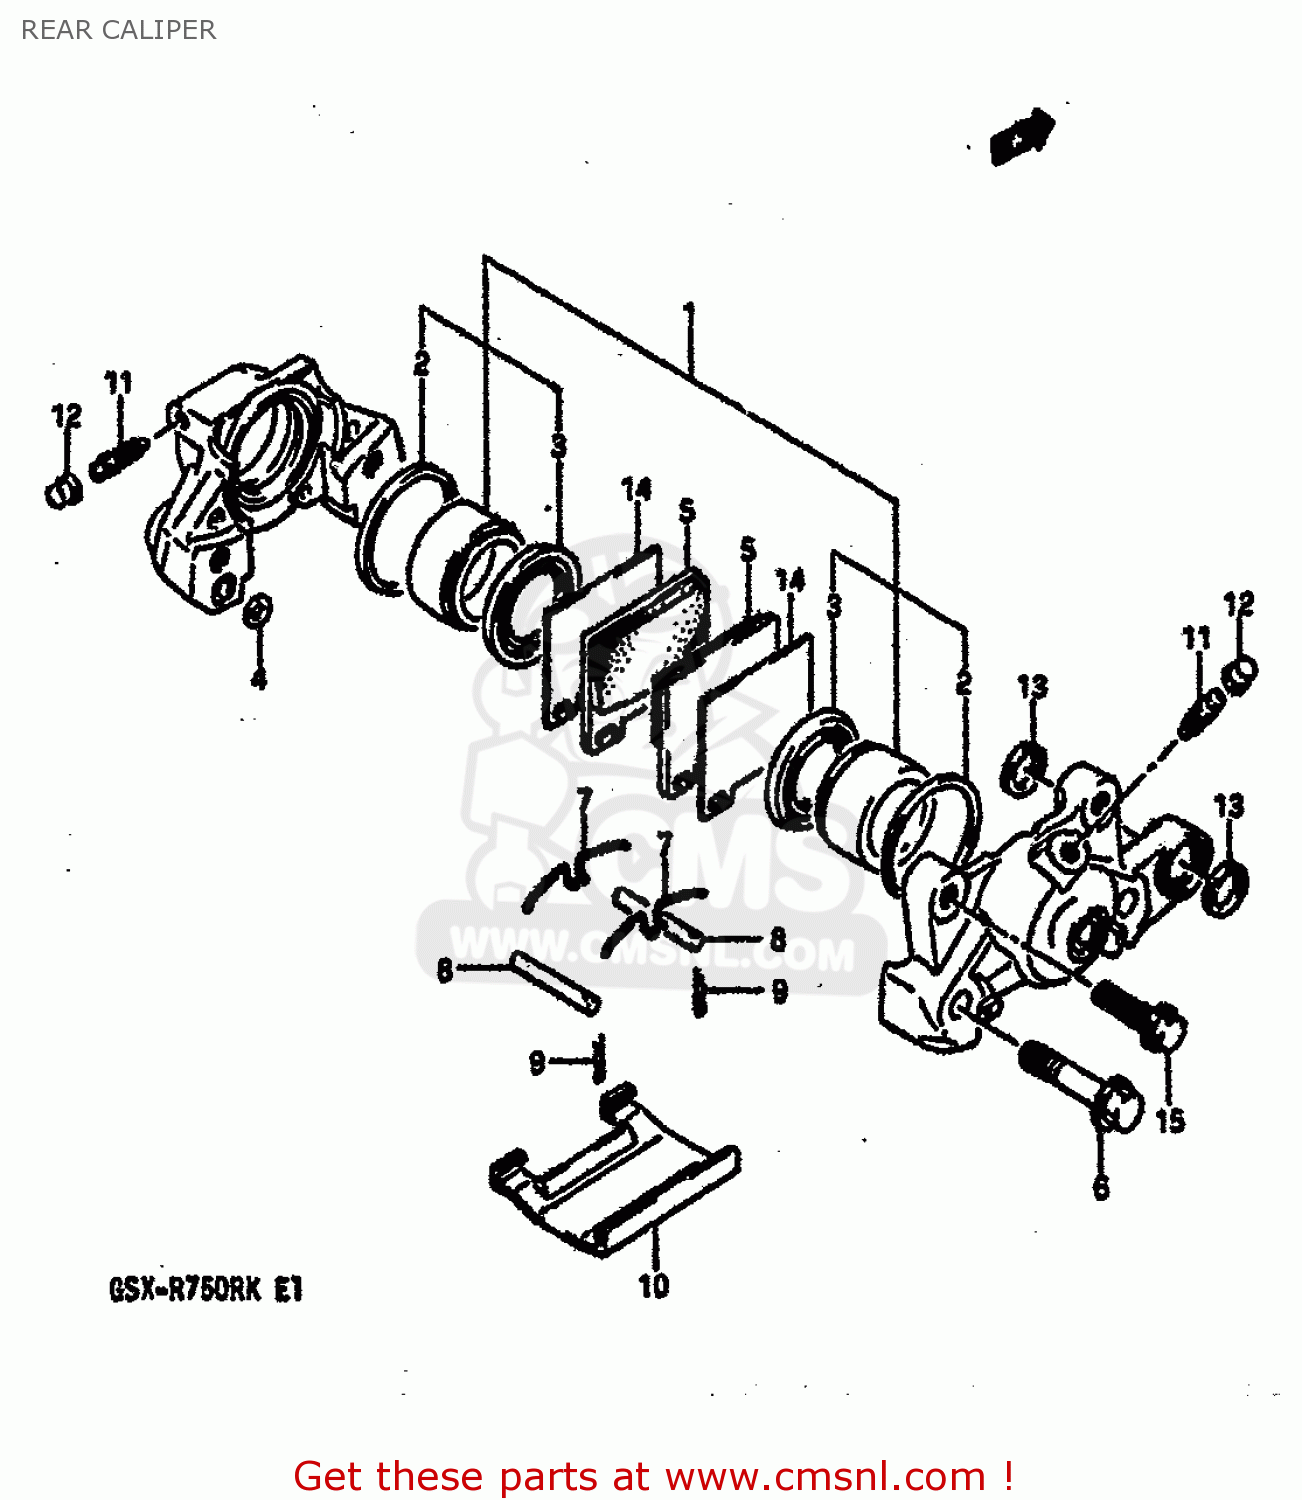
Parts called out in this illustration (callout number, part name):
1	PISTON SET
2	SEAL,PISTON
3	BOOT
4	SEAL,JOINT
5	PAD,BRAKE
6	BOLT
7	SPRING
8	PIN,PAD
9	CLIP,PAD PIN
10	COVER
11	BLEEDER
12	CAP,BREATHER
13	SEAL,RR CUSHION ROD LWR
14	SHIM,PAD
15	BOLT
